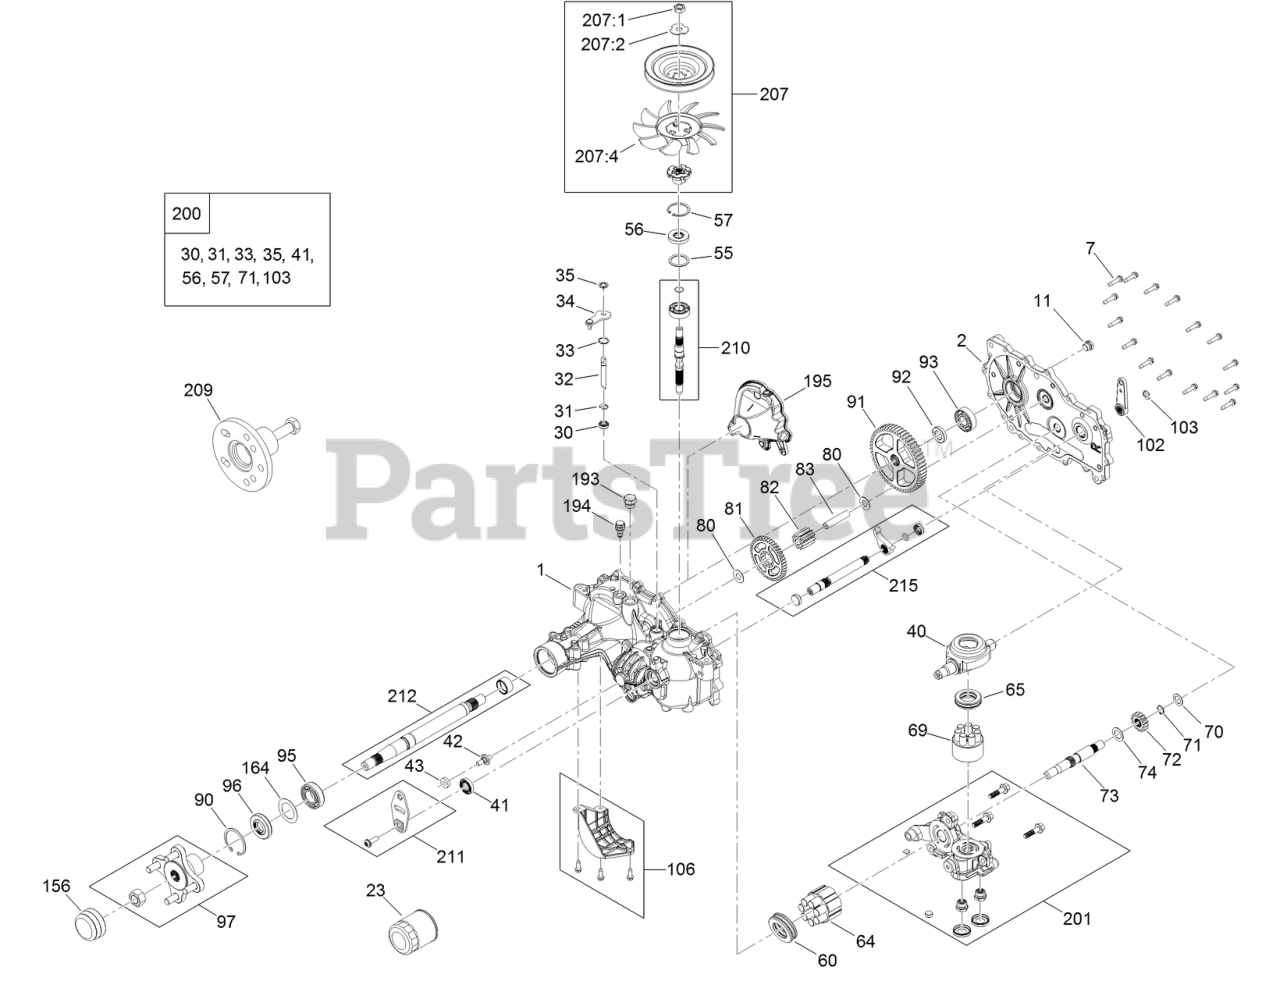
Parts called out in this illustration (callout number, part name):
1	KIT-HOUSING MAIN RH, CNTL
2	RH SIDE COVER KIT
7	SCREW-HHF
23	ELEMENT-OIL FILTER, HYD
30	SEAL-LIP
31	RING-RETAINING, EXTERNAL
32	ROD-BYPASS
33	RING-RETAINING, INTERNAL
35	RING-RETAINING, EXTERNAL
40	SWASHPLATE-TRUNNION
41	SEAL-LIP
43	PUCK-FRICTION
55	SPACER
56	SEAL-LIP
57	RING-RETAINING
60	BEARING-THRUST
64	CYLINDER BLOCK ASM KIT
65	BEARING-THRUST
69	PUMP BLOCK ASM
70	WASHER-FLAT
71	RING-RETAINING
72	GEAR-16T
73	SHAFT-MOTOR
74	WASHER
80	WASHER
81	GEAR-43T
82	GEAR-11T
83	PIN-JACKSHAFT
90	RING-RETAINING
91	GEAR-54T
92	SPACER
93	BEARING KIT
95	BEARING-BALL
97	HUB KIT
102	HANDLE-BRAKE
103	RING-RETAINING, EXT
106	FILTER GUARD KIT
156	COVER-NUT, AXLE
164	SPACER
194	BREATHER FITTING ASM
195	RH INTERNAL EXPANSION TANK ASM
200	SEAL KIT
201	RH CENTER SECTION KIT
207	FAN AND PULLEY KIT
210	KIT-INPUT SHAFT
211	CONTROL ARM KIT
212	AXLE SHAFT KIT
215	INBOARD KIT
